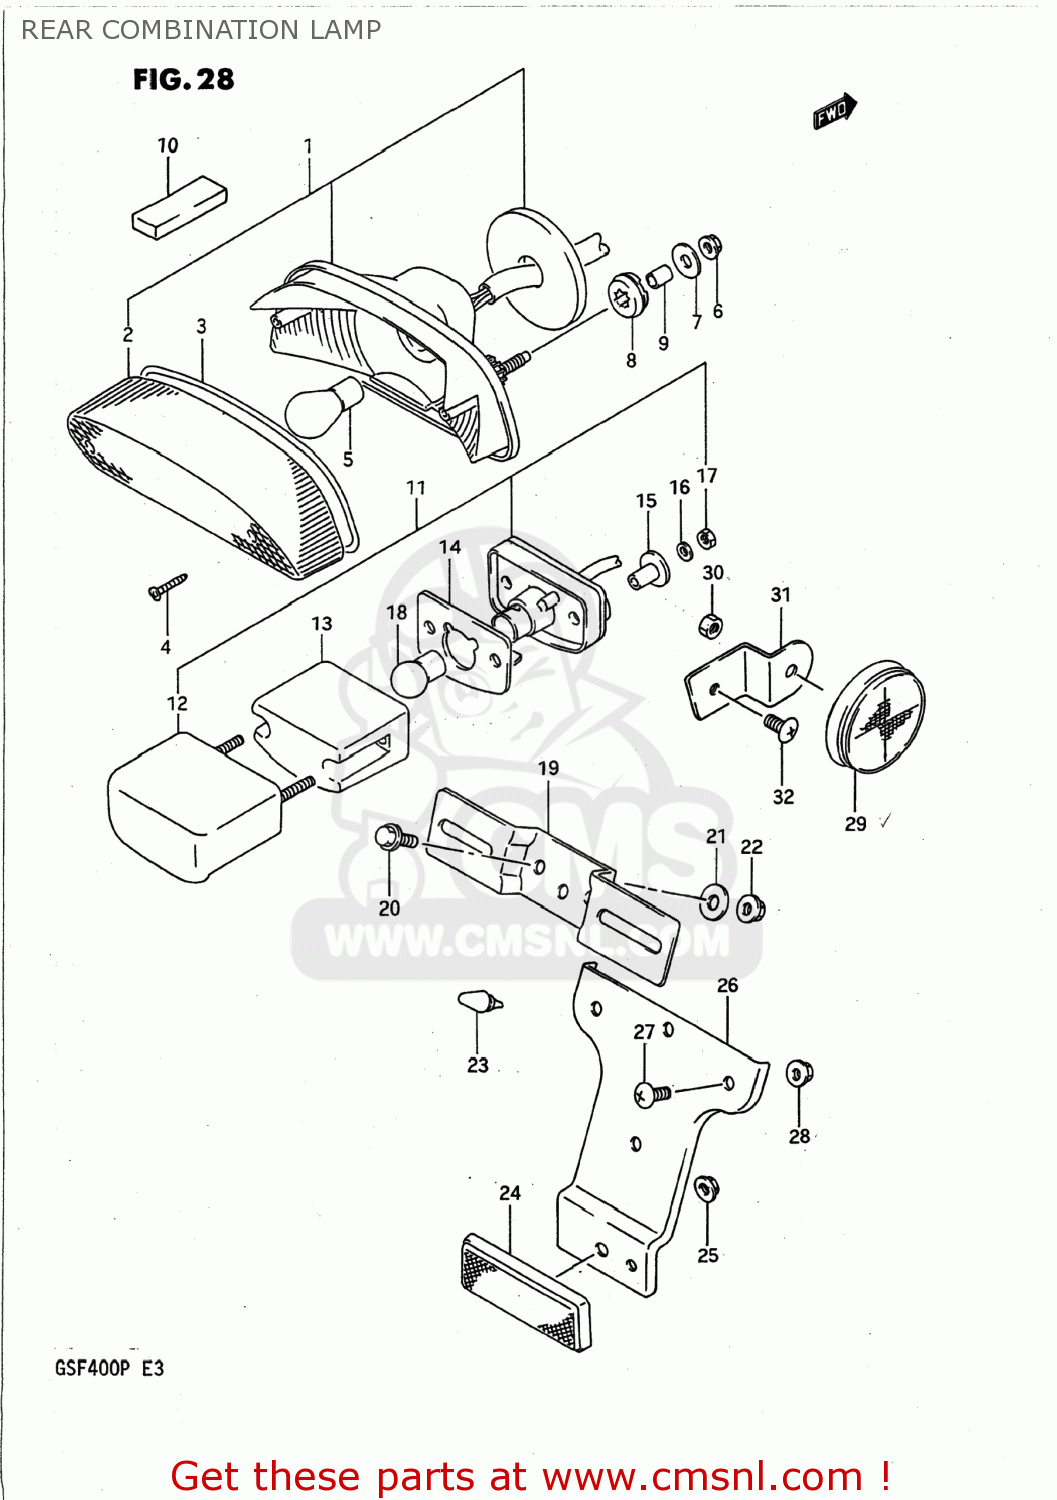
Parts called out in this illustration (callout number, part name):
1	LAMP ASSEMBLY,REAR COMBINATION
2	LENS
3	GASKET (NAS)
4	SCREW
5	BULB(12V21/5W)
6	NUT
7	WASHER
8	CUSHION
9	SPACER
10	CUSHION,REAR LENS
11	LAMP ASSEMBLY,LICENSE
12	COVER,LICENSE LAMP
13	LENS
14	GASKET,LICENSE LAMP (NAS)
15	SPACER
16	WASHER,LOCK 4M
17	NUT
18	BULB
19	BRACKET,LICENSE PLATE
20	BOLT
21	WASHER,COVER,FRONT
22	NUT
23	CUSHION
24	REFLECTOR ASSEMBLY,REAR
25	NUT 5MM
26	BRACKET,REAR REFLECTOR
27	SCREW 6X12
28	NUT
29	REFLEX REFLECTOR,RR
30	NUT
31	BRACKET,REAR SIDE REFLECTOR
32	SCREW
